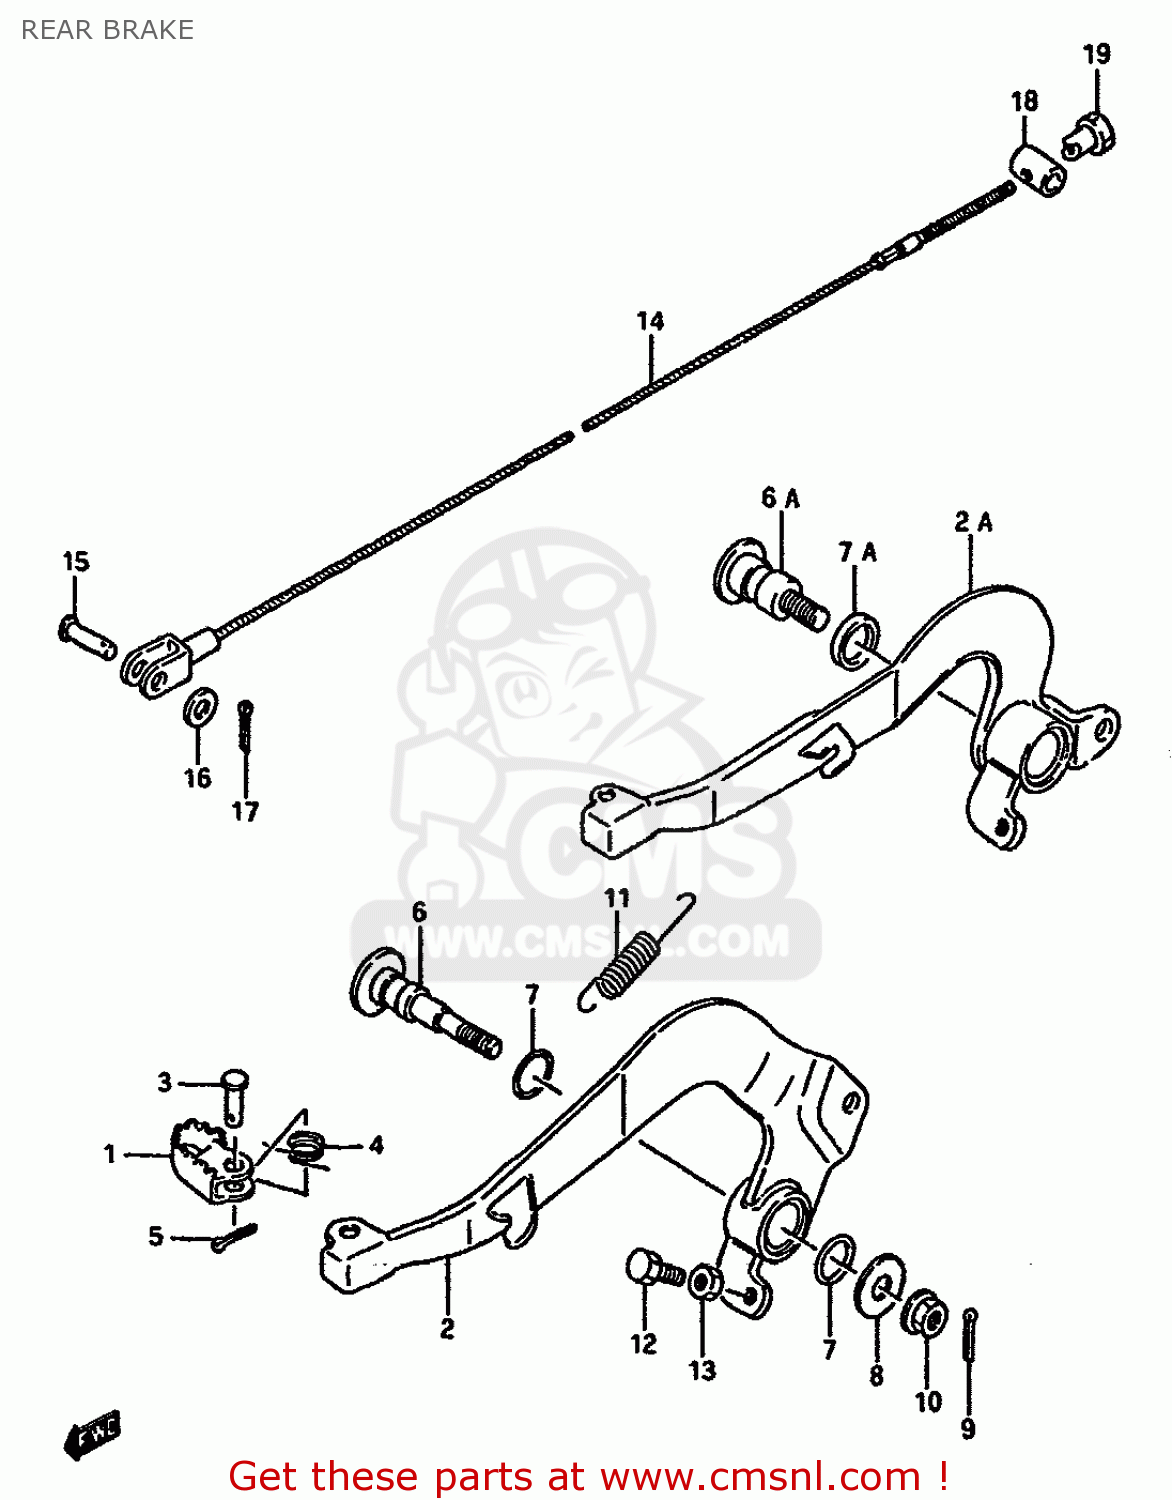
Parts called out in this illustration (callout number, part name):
1	PEDAL,BRAKE
2	ARM,BRAKE PEDAL
2A	ARM COMP,BRAKE PEDAL
3	PIN
4	SPRING
5	PIN
6	SHAFT,BRAKE PEDAL
6A	SHAFT,BRAKE PEDAL
7	O-RING,BOSS
7A	SEAL,OIL(15X20X3)
8	WASHER
9	PIN 20X20
10	NUT
11	SPRING BRAKE PEDAL
12	BOLT
13	NUT
14	CABLE,RR BRAKE
15	PIN(L:17.5)
16	WASHER
17	PIN 20X20
18	PIN
19	NUT (6MM)
